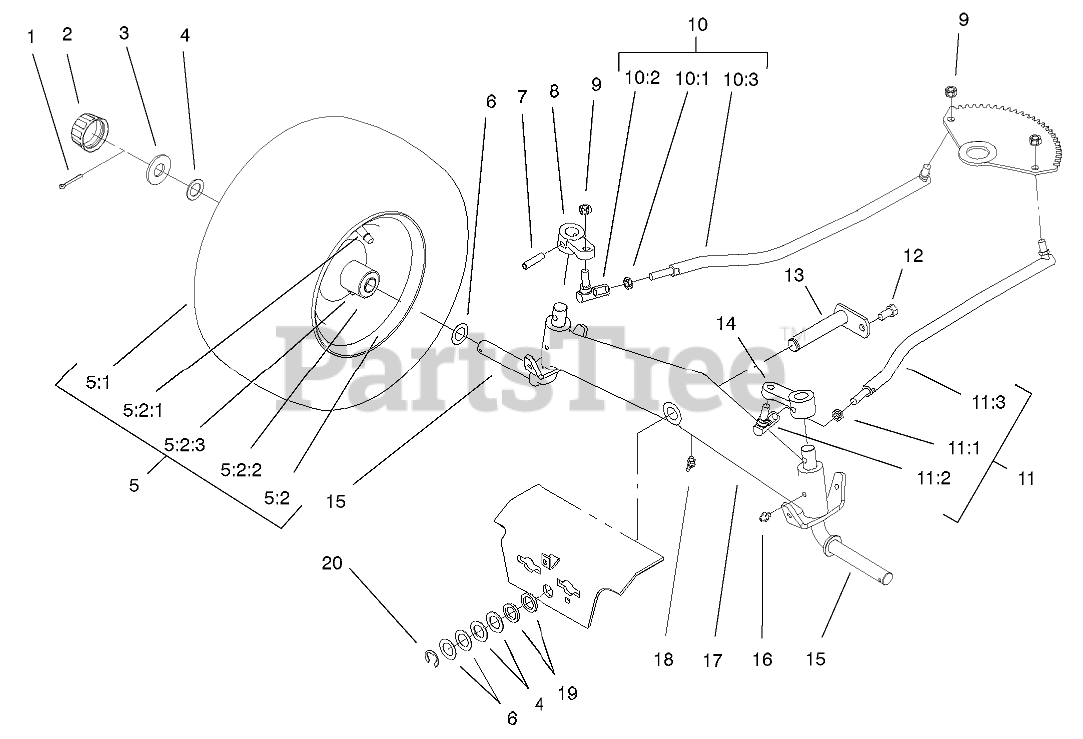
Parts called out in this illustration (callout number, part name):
1	PIN-COTTER
2	CAP-HUB
3	WASHER-PLAIN
4	WASHER
5	Front Wheel & TireASM
5:2	Wheel ASM
5:2:1	VALVE
5:2:2	BEARING-WHEEL
5:2:3	ZERK-GREASE
6	WASHER-SHIM
8	Arm-Front Spindle
10	LINKAGE-STEERING, RH
10:1	NUT-JAM
10:2	BALL-JOINT
10:3	Ball Link ASM
11	LINKAGE-STEERING, LH
11:1	NUT-JAM
11:2	BALL-JOINT
11:3	Ball Link ASM
12	SCREW-HWH, TAPTITE
13	PIN-AXLE
14	Arm-Front Spindle
15	SPINDLE
16	FITTING-GREASE
17	AXLE-FRONT
18	FITTING-LUBE, 45 DEG
19	Washer
20	E-RING
